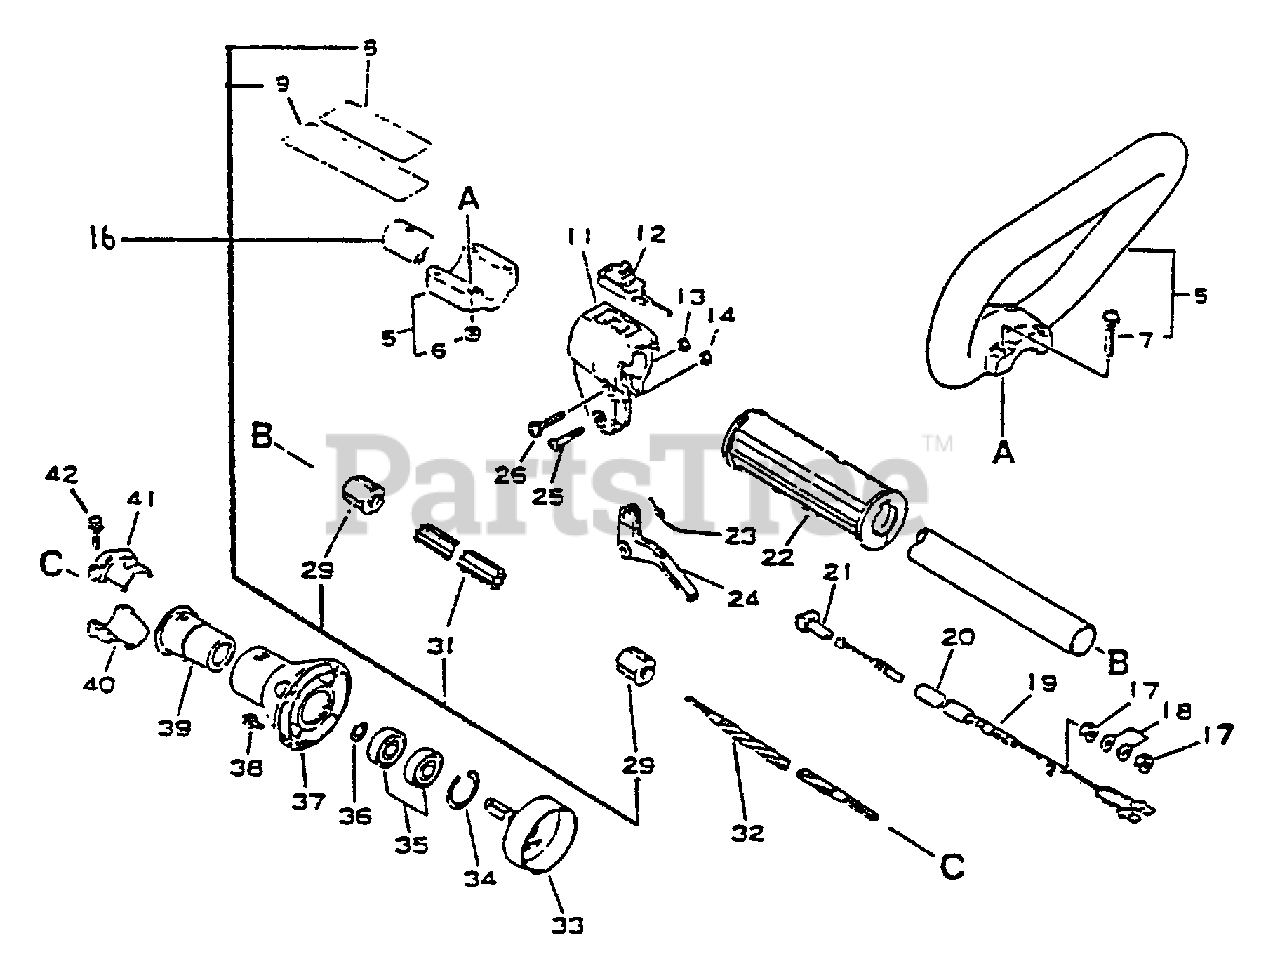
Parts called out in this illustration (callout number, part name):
5	LOOP HANDLE ASSY
7	SCREW - 5X35
8	LABEL - CAUTION
9	LABEL - CAUTION
11	BRACKET, THROTTLE CONTROL
12	IGNITION SWITCH ASSY
14	LOCKNUT - 5
16	MAIN PIPE ASSY
18	WASHER - 6
19	CABLE, THROTTLE
20	TUBE - VINYL
21	GUIDE, CABLE
22	GRIP, HANDLE
23	SPRING, TRIGGER
24	TRIGGER, THROTTLE
25	SCREW - 5X30
26	SCREW - 5X30
31	LINER - FLEXIBLE
32	DRIVESHAFT - FLEXIBLE
33	DRUM, CLUTCH
34	RING, RETAINING - 28
35	BEARING, BALL - 6001
36	RING, RETAINING - 12
37	CASE, CLUTCH - ORANGE
38	SCREW - 5X16
40	CLAMP, MAIN PIPE - UPPER
41	CLAMP, MAIN PIPE
42	BOLT - 5X25
